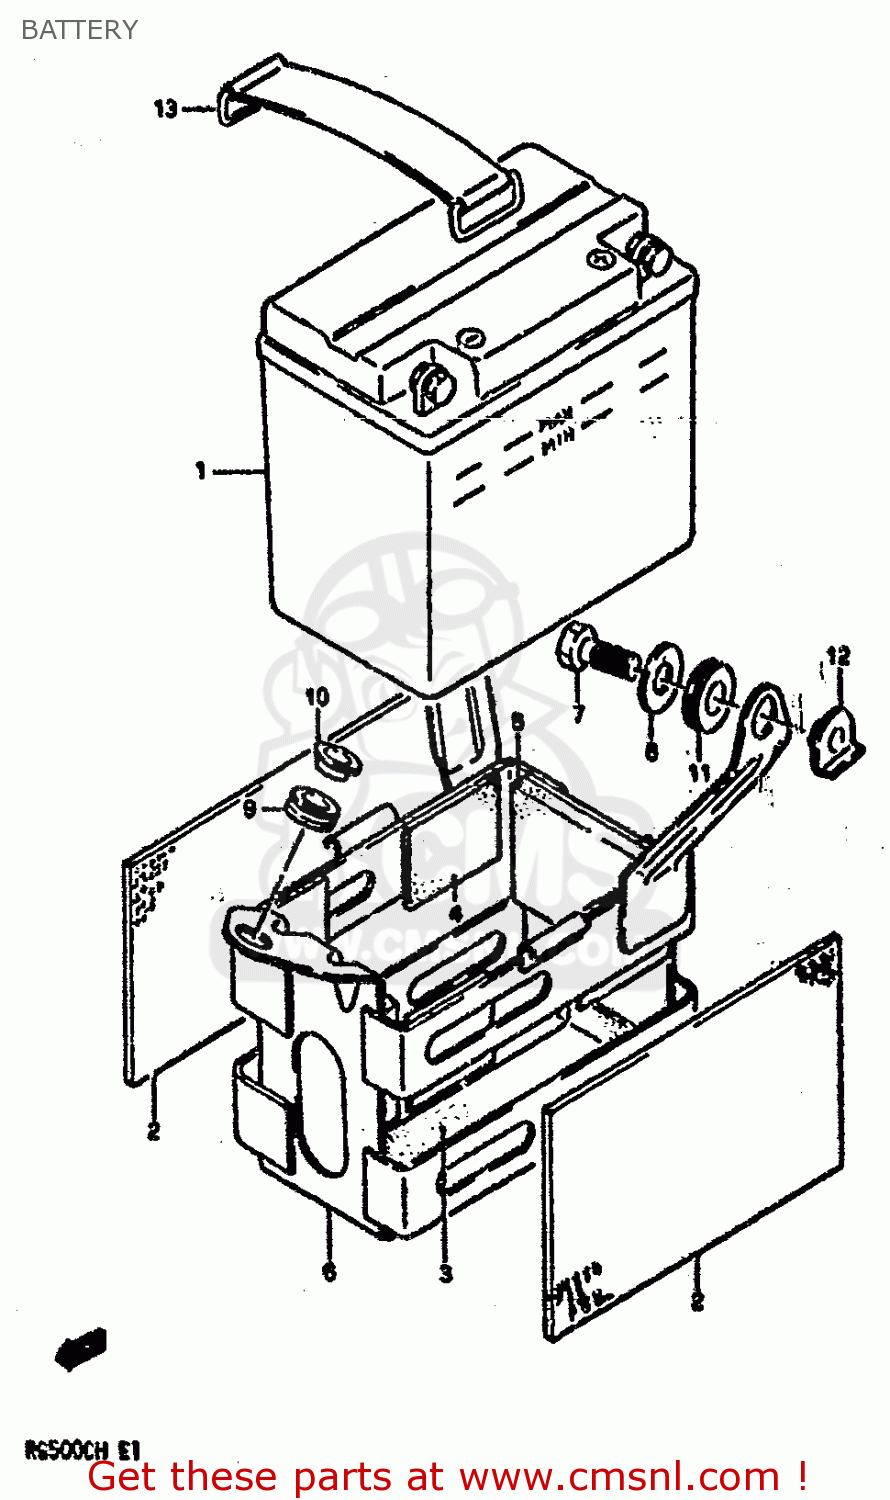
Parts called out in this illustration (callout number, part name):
1	BATTERY (YT5L-12,12V4AH)
2	PROTECTOR,BATTERY
3	PROTECTOR(170X95X3.0)
4	PROTECTOR(170X95X3.0)
5	PROTECTOR,BATTERY (40X50X6)
6	HOLDER,BATTERY
7	BOLT
8	WASHER (6.5X20X1.2)
9	CUSHION
10	WASHER
11	CUSHION
12	WASHER
13	BAND
